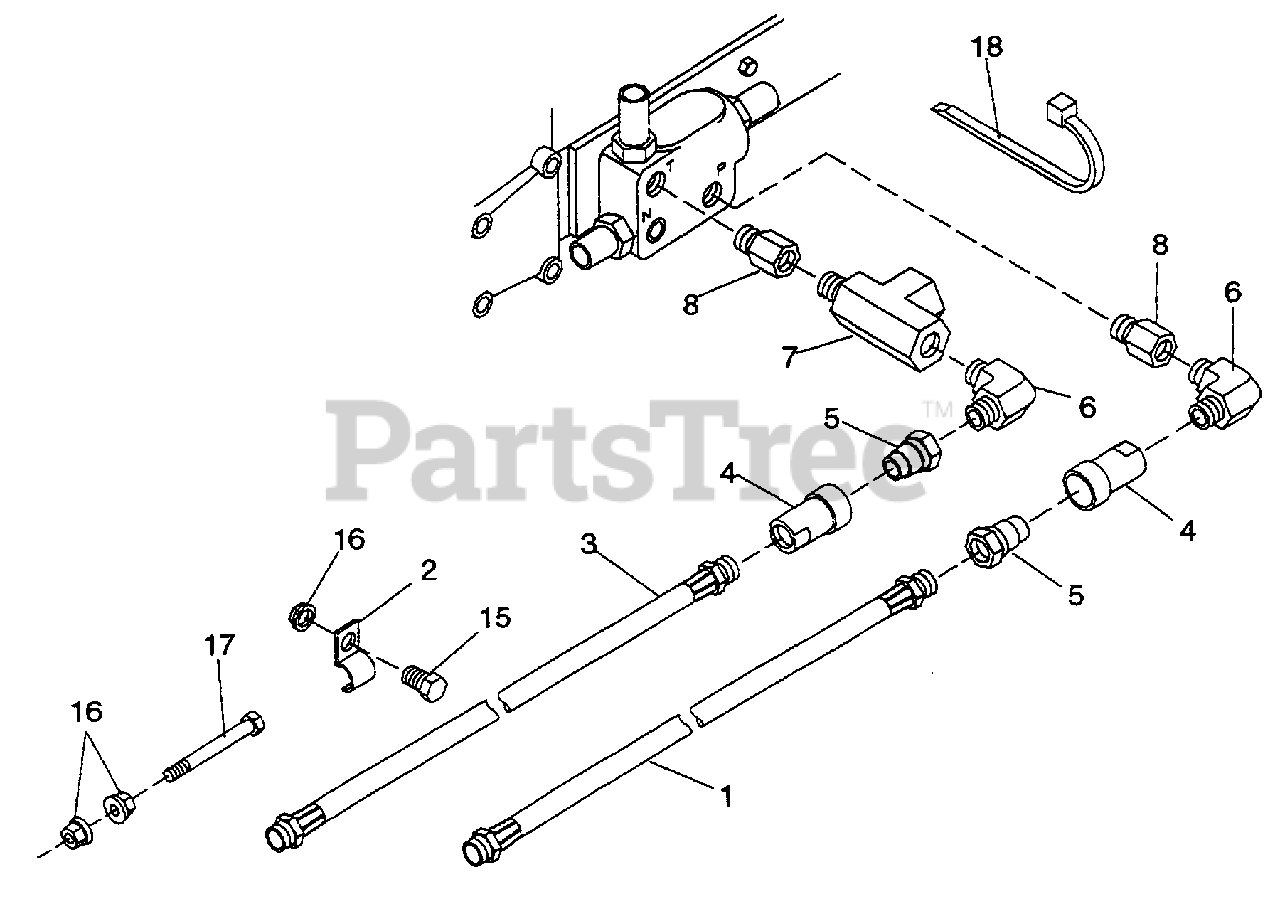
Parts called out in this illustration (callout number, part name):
1	Hose, 3/8 NPT x 92"
2	Hose clamp
3	Hose, 3/8 NPT x 100"
4	Quick coupler, 3/8 NPT female
5	Quick coupling, 3/8 NPT male
6	Elbow, Male 3/8 NPT x 90°
7	Run tee, 3/8 NPT
8	Adapter, 3/8 BSTP Male 3/8 NPT
15	1/4 NC x 3/4 Hex head cap screw GR5
16	1/4 NC Flanged locknut
17	1/4 NC x 4 Hex head cap screw GR5
18	Hydraulic hose tie, 7" long
